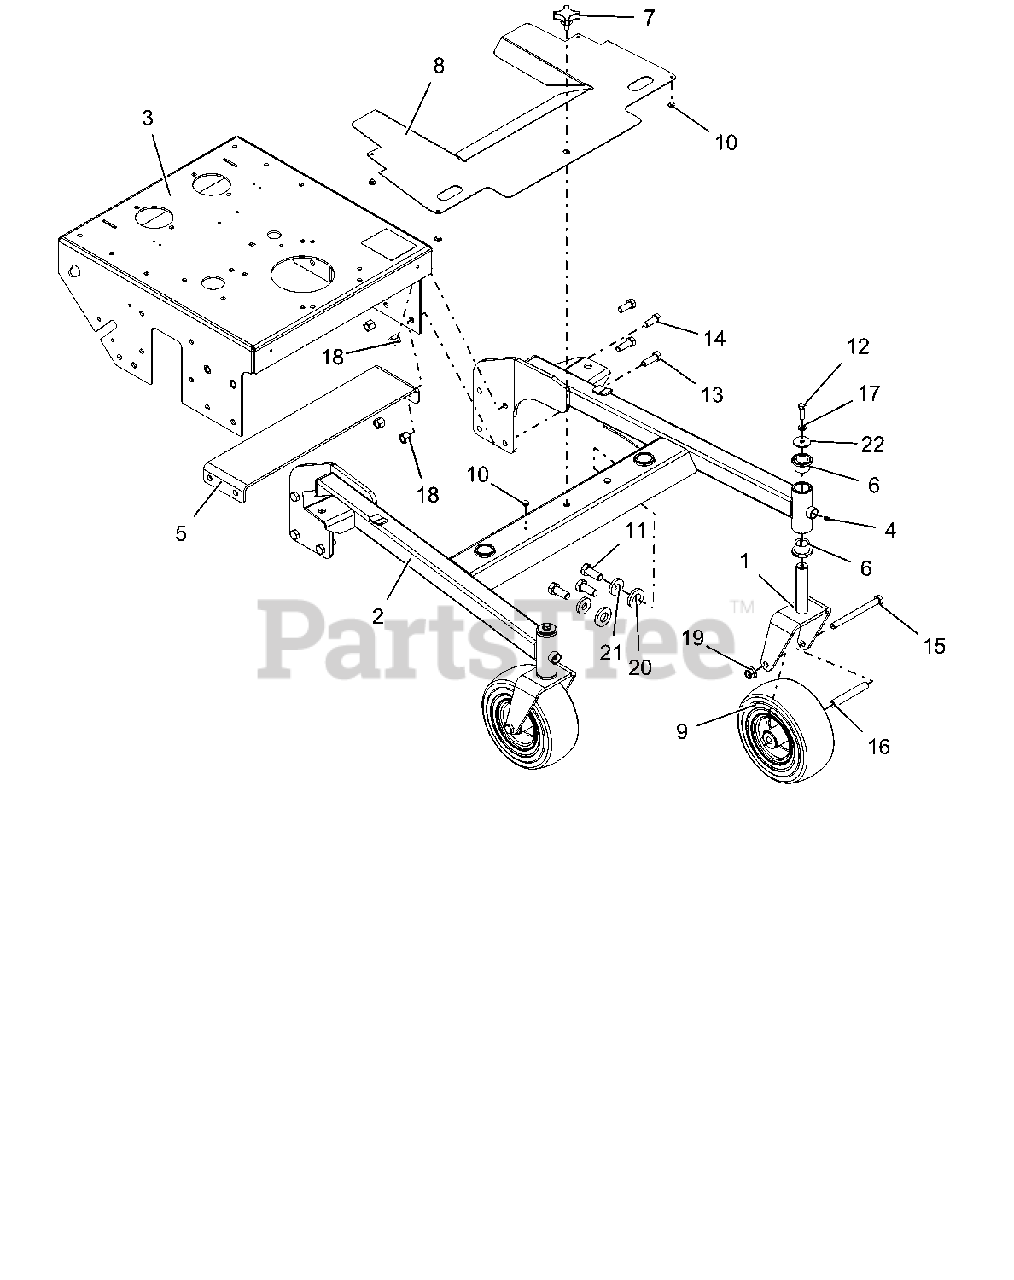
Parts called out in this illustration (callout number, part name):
1	WLDMT, FRONT WHEEL FLOAT WALK
2	WLDMT, DECK FRAME 48 FLWLK
3	ASSM, 48-52" FRAME W/DECALS
4	FTG, 1/4-28 STRGT GREASE ZERK
5	PLATE, ENGINE BED FRONT 48/52-RED
6	BRG, FLANGE 1.00 X 1.25 X 1.00
7	KNOB, 3/8-16 x .75
8	SHIELD, BELT 48" HYDRO WALK
9	9X3.5-4 CAREFREE BLT TOGETHER
10	BUMPER GROMMET .125 X .25 REV
11	BLT-HEX .62-11X1.50 GR8 YWZC
12	BLT-HEX .38-16X1.25 GR5 YWZC
13	BLT-HEX .50-13X1.50 GR5 YWZC
14	BLT-HEX .50-13X1.25 GR5 YWZC
15	BLT-HEX .50-13X5.50 GR5YWZC
16	TUBE, CASTER AXLE
17	WSHR-LK .38X.094 REG YWZC
18	NUT-LK-NYL .50-13 YWZC
19	NUT-LK-NYL-FLG .50-13 YWZC
20	WSHR-FL-STL .905X1.750X.25 YWZC
21	WSHR-FL-STL .630X1.50X.25 YWZC
22	WSHR-FL-STL .380X1.50X.125 YWZC
